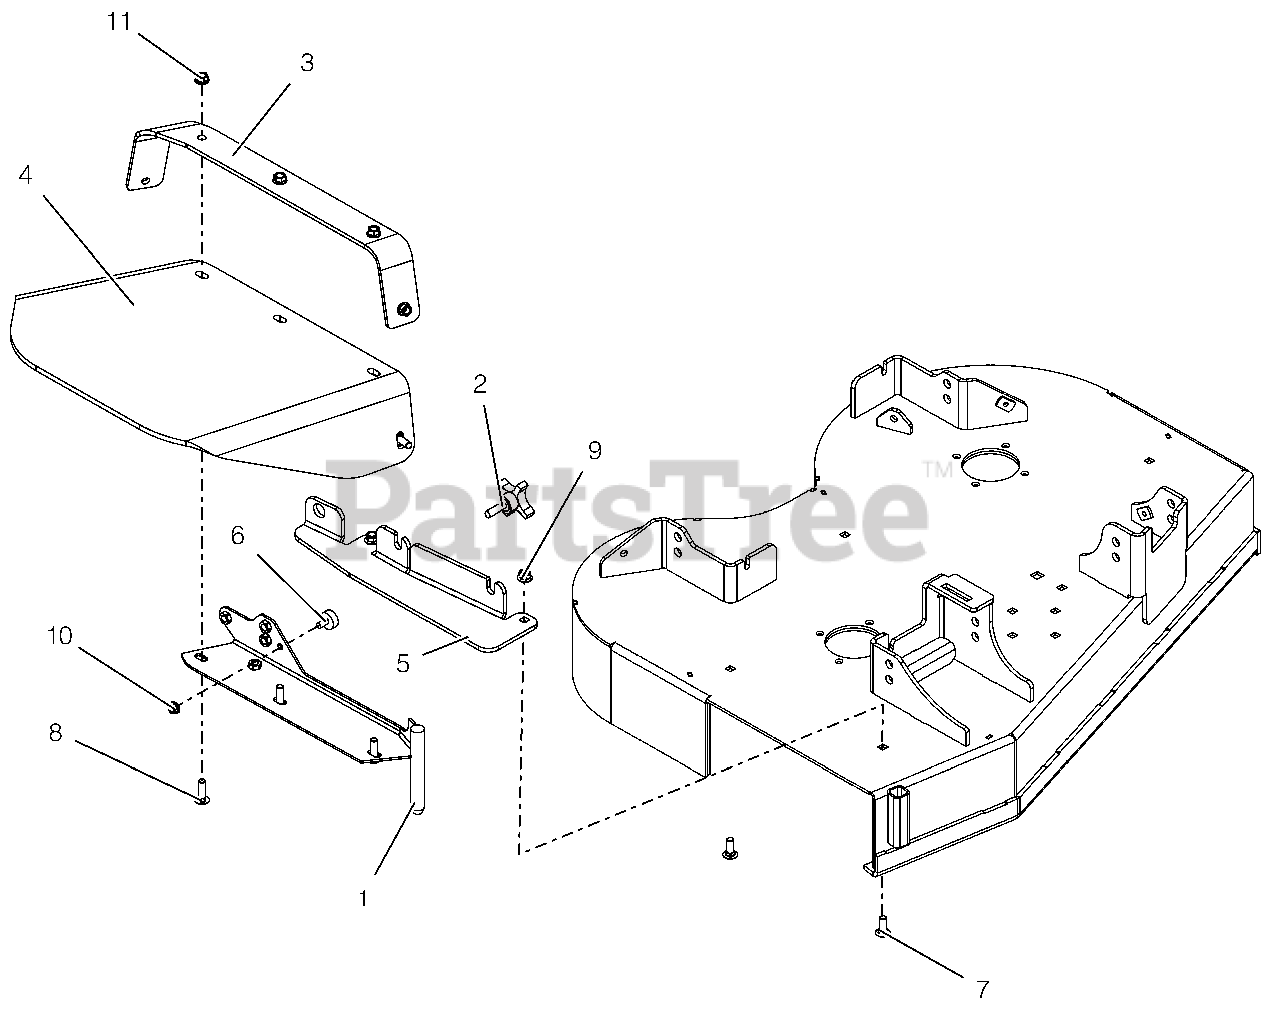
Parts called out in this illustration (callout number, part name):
1	WLDT. DISCHARGE
2	KNOB, 3/8 X 1.25 - 4 PRONG
3	STRAP, RUBBER DISCHARGE CHUTE
4	SHIELD, RUBBER DISCHARGE
5	BRKT, 36 STANCE DISCHARGE
6	BUMPER, RUBBER
7	@BLT-RDHDSQNK .38-16X1.00 G5YZ
8	@BLT-RDHDSQNK .38-16X1.25 G5YZ
9	@NUT-LK-NYL-FLG .38-16 YWZC
10	@NUT-SPNLK-FLG .312-18 YWZC
11	@NUT-SPNLK-FLG .375-16 YWZC
